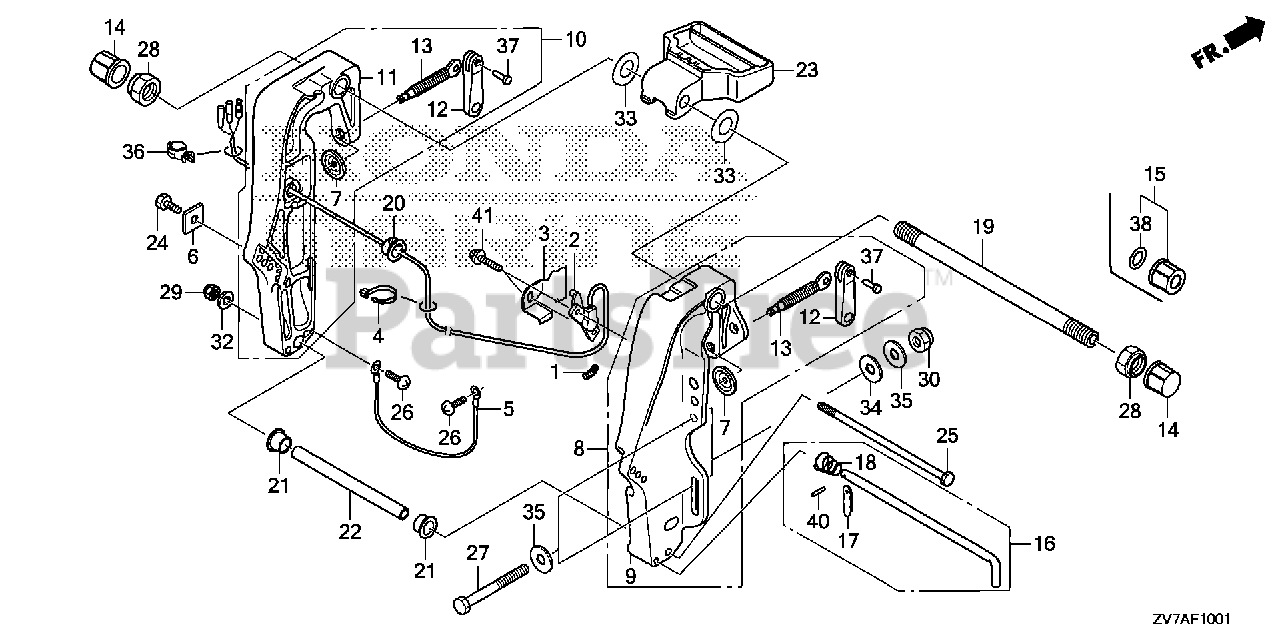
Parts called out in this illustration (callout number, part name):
5	WIRE, LEAD (1.5X170MM)
6	METAL, ANODE
7	PLATE, PUSH
8	BRACKET, R. STERN *NH282MU* (OYSTER SILVER METALLIC-U)
9	BRACKET, R. STERN *NH282MU* (OYSTER SILVER METALLIC-U)
10	BRACKET, L. STERN *NH282MU* (OYSTER SILVER METALLIC-U)
11	BRACKET, L. STERN *NH282MU* (OYSTER SILVER METALLIC-U)
12	GRIP, CLAMP
13	SCREW, CLAMP
14	CAP, TILTING BOLT
16	ROD, ADJUSTING
17	STOPPER, ROD
18	SPRING, ADJUSTING ROD
19	SHAFT, TILTING
21	BUSH, CYLINDER (LOWER)
22	COLLAR, CYLINDER (LOWER)
23	HANDLE, CARRYING
24	BOLT, FLANGE (6X12)
25	BOLT, HEX. (8X203)
26	SCREW, PAN (6X8)
28	NUT, SELF-LOCK (7/8-14UNF)
29	NUT, SELF-LOCK (8MM)
32	WASHER, PLAIN (8MM)
33	WASHER, WAVE (22MM)
37	RIVET (4X22.6)
40	PIN, SPRING (2.5X8)
